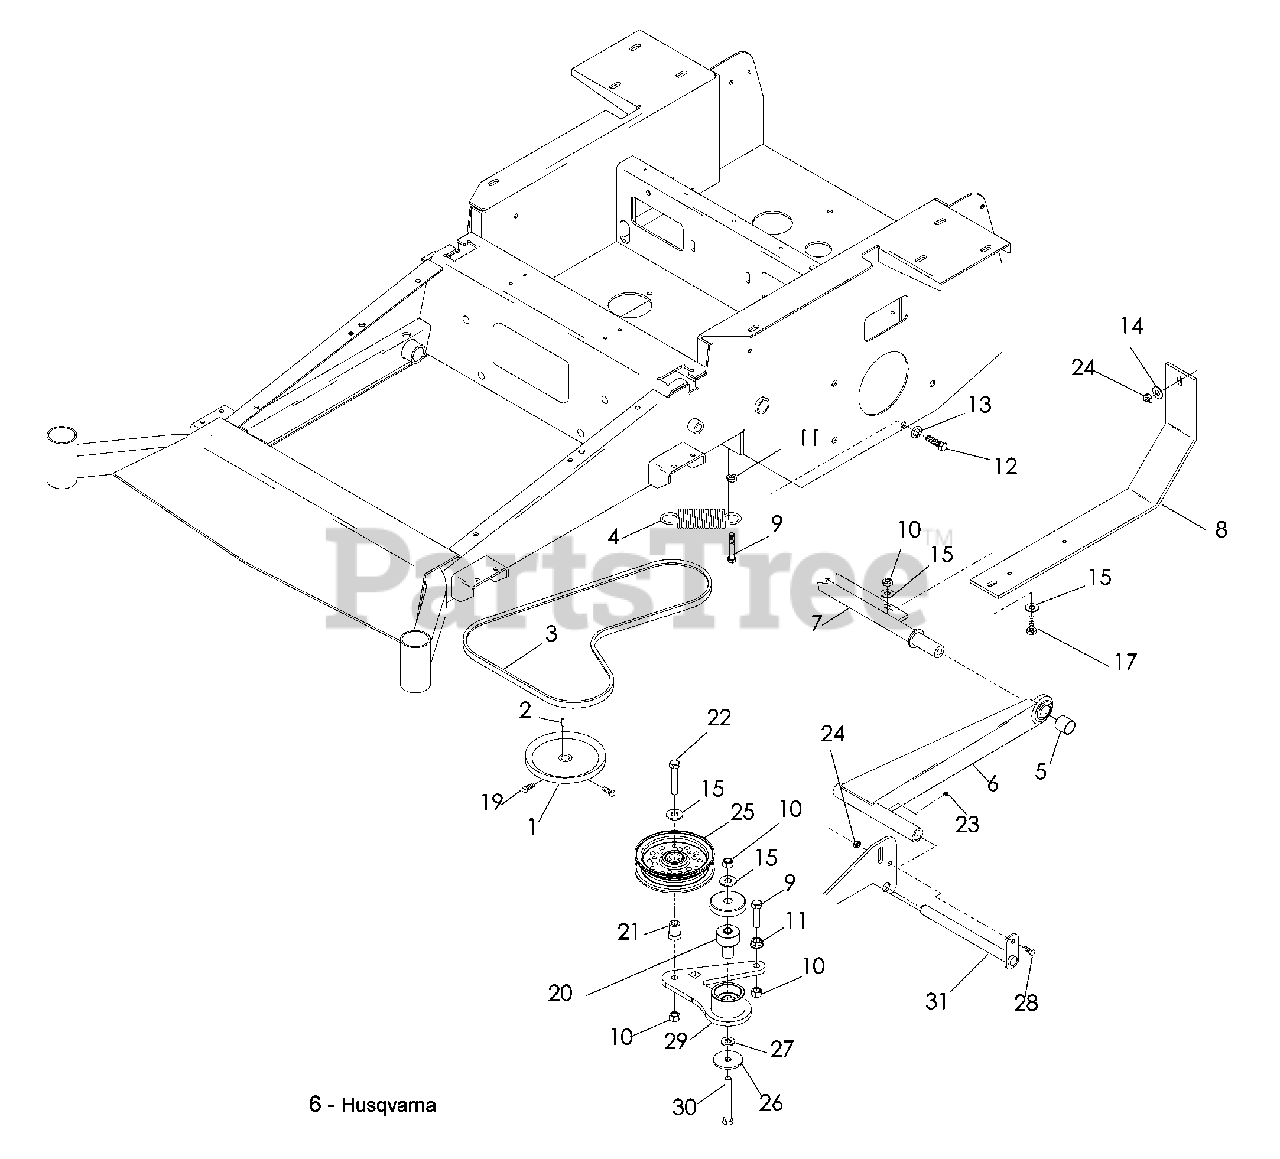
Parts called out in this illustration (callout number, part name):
3	BELT, PUMP
5	STRUT SPACER
6	STRUT WELDMENT, REAR
7	CROSS SHAFT
8	SKID PLATE
9	HCS 3/8-16 x 1½
10	NUT 3/8-16 HEX NYLOC
11	NUT 3/8-16 HEX WHIZLK
12	BOLT, BLADE W/WASHER
13	LOCKWASHER 7/16
14	WASHER 5/16 STD FLT
15	WASHER 3/8 STD FLT
16	HCS ½-13 x 3¼
17	HCS 3/8-16 x 1
18	NUT ½-13 HEX NYLOC
19	SCREW, SET
20	PIVOT, BEARING
21	IDLER FLANGE BUSHING
22	HCS 3/8-16 x 2
23	ZERK
24	NUT 5/16-18 HEX NYLOC
25	PULLEY, IDLER
26	WASHER 3/8 SPEC
27	WASHER 3/8 SAE FLT
28	HCS 5/16-18 x 1
29	ARM, IDLER
30	HCS 3/8-16 x 3
31	PIVOT PIN WELDMENT
